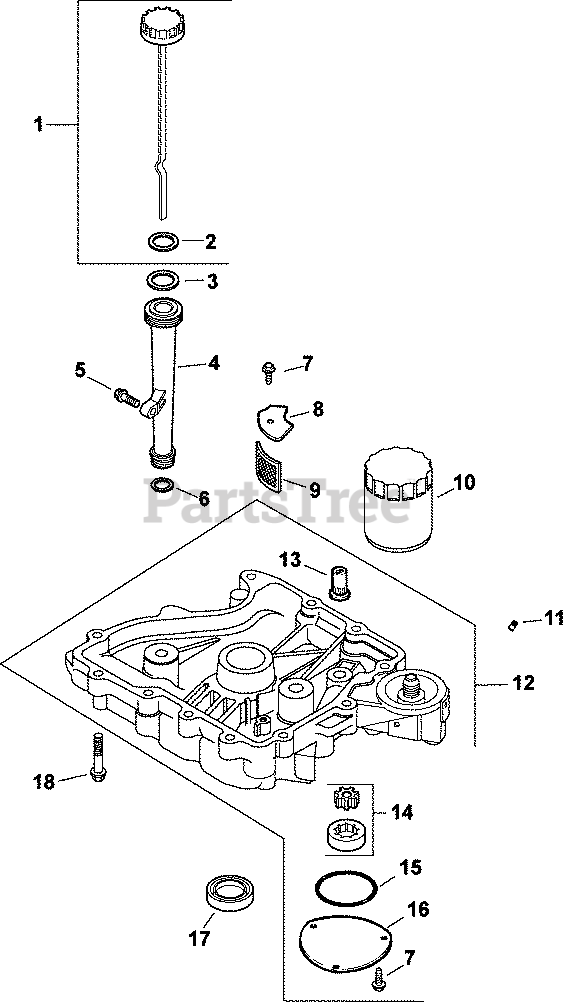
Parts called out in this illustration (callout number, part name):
1	DIPSTICK/CAP ASSY (BLACK)
2	O-RING, DIPSTICK
3	O-RING, UPPER OIL FILL TUBE
4	TUBE, OIL FILL USE 25 123 07-S
5	SCREW,FLG THD FRM M6X1.0X25-(#25086395S)
6	O-RING, LOWER OIL FILL TUBE
7	SCREW,FLG THD FRM M5X0.8X16-(#25086398S)
9	SCREEN, OIL-USE 24 162 26-S
10	OIL FILTER
11	PLUG, SQ HD PIPE 3/8"
12	PAN, OIL ASSEMBLY - DISCONTNUED
13	VALVE, OIL PRESSURE RELIEF
14	PUMP ASSEMBLY, OIL - DISCONTINUED
15	O-RING (2.5" DIA)
16	COVER, OIL PUMP
17	SEAL, OIL
18	SCREW, FLG M8X1.25X45
